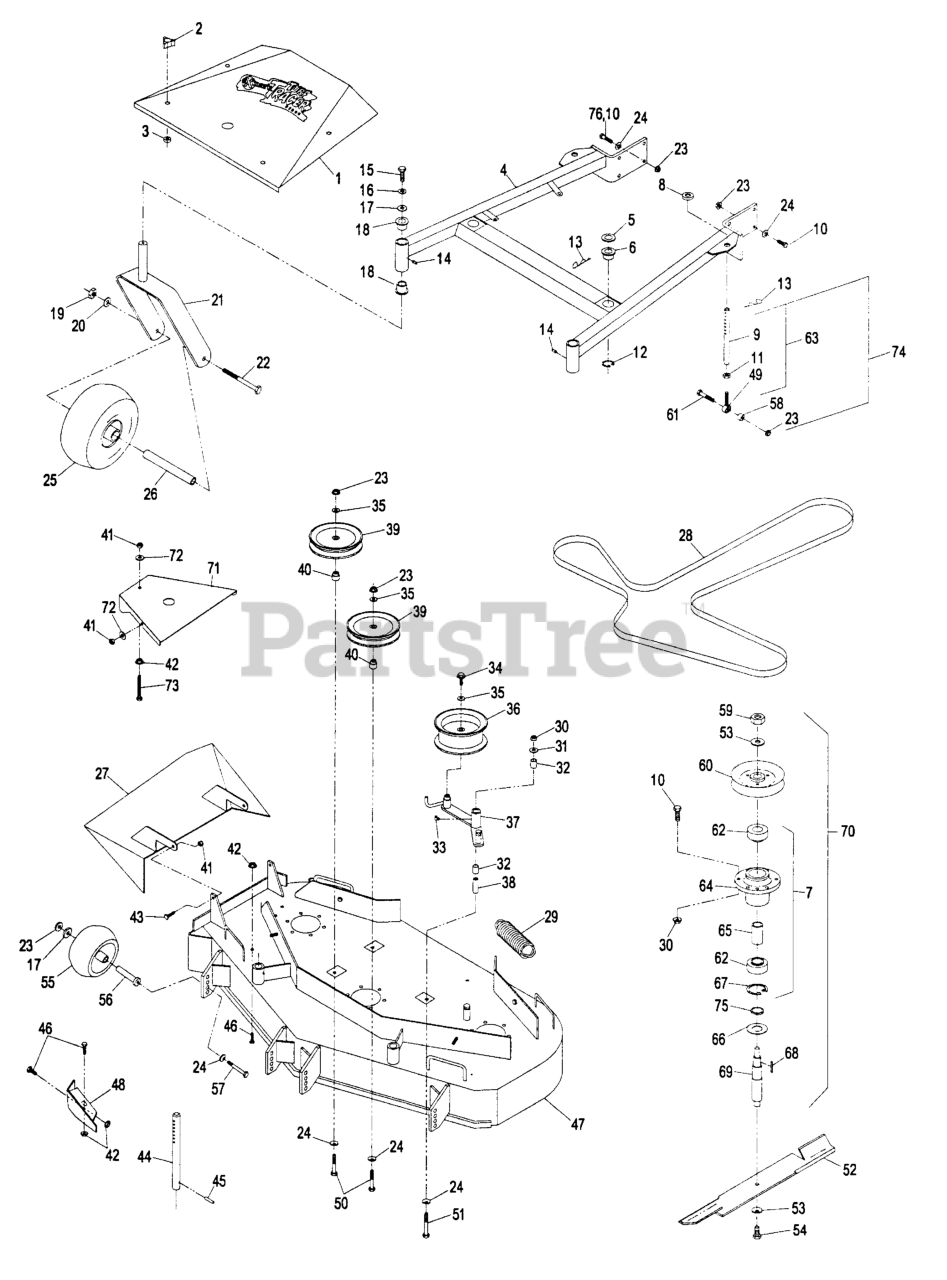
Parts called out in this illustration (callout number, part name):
2	KNOB-3 PRONG
4	DECK SUPPORT W/BSHGS 48"
5	SPACER-DECK SUPPORT
6	BUSHING-DECK
9	LINK,SUPPORT
13	PIN,HAIR COTTER
18	BEARING-FLANGED
24	WASHER-BELLEVILLE
28	BELT - V, B
32	SLEEVE-BEARING
38	BUSHING-PIVOT, IDLER
39	PULLEY-IDLER
40	BUSHING-IDLER
44	ROD,DECK SUPPORT
47	ASM,DECK W/DECALS TTHP/MH
49	BALLJOINT
51	SCREW-HH
53	WASHER-SPRING
55	ROLLER-SCALP, ANTI
56	BUSHING-ROLLER
60	SHEAVE,W/HUB 5.72
62	BEARING
65	SPACER-BEARING
66	GUARD-BEARING, BOTTOM
68	KEY-RECTANGLE
69	SHAFT,SPINDLE
70	HOUSING,CUTTER COMPLETE
73	BOLT,TAP HH
75	SPACER-PULLEY/BEARING
